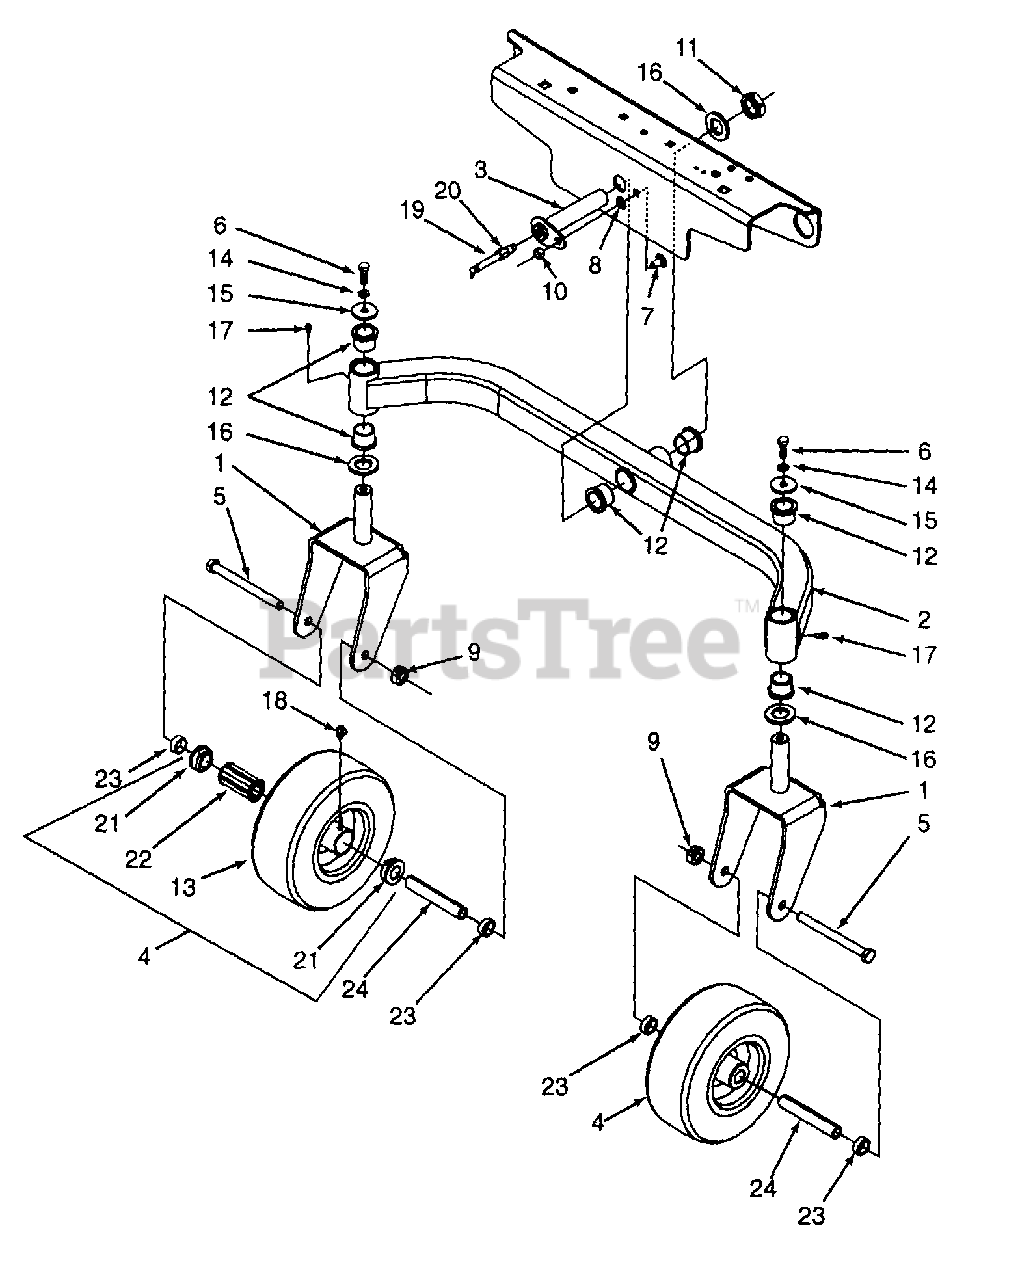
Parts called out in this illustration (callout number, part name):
4	Wheel Comp 11.0 x 4.0 x 5.0
5	Screw, Hex Cap, 1/2-20 x 5.5
6	Screw, Hex Cap, 3/8-16 x 1.0 GR5
7	Bolt, Carriage, 3/8-16 x .75
8	Push Nut, Retainer, 3/8 ID
9	Nut, Hex Center Lock, 1/2-20
10	Nut, Hex Flange Lock, 3/8-16
11	Nut, Hex Lock, 1.0-14
12	Bearing, Flange, 1.0 ID
13	Tire, Urethane, Only
14	Washer, Lock 3/8
15	Washer, Flat, .39 x 1.5 x .134
16	Washer, Special Flat
17	Fitting, Grease
18	Fitting, Grease, 90° Tap 1/4-28
19	Fitting, Grease, 65° w/Extension
20	Adapter, 1/8 NPTF x 1/8 NPTF
21	Bearing, Flange
22	Bearing, Roller
23	Spacer, .79 ID x .347 Lg
24	Spacer, Wheel
